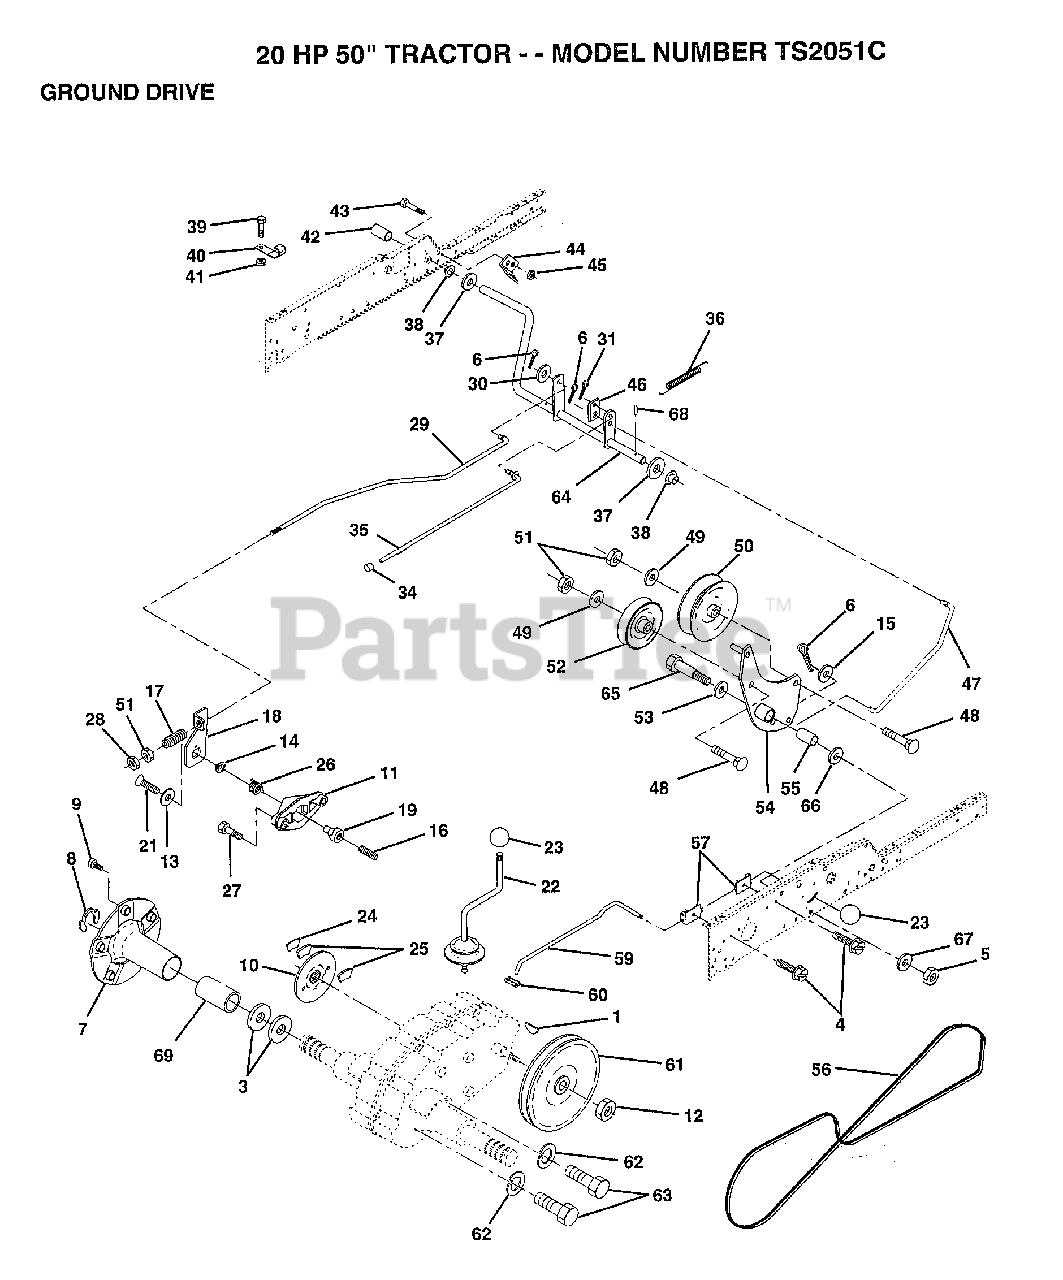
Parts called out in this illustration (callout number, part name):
3	WASHER T
6	COTTER PIN
8	KLIP RING
9	BOLT.HUB.WHL.REAR
11	YOKE BRAKE DISC
12	NUT STD
13	WASHER SPECIAL
14	BUSHING LEVER BKT
15	WASHER
16	SCREW SET 1/4-20
17	"SPRING,ROD BRAKE"
18	LEVER BRAKE GT
19	CAM BRAKE DISC GT
20	BOLT
21	SCREW FLT 1/4X28
22	GEAR SHFT LVR T
23	KNOB
24	SUPPORT PUCK BRKE
25	PUCK BRAKE TOP
26	SPRING RET BRAKE
27	SCREW HX WASH
28	NUT
29	ROD BRAKE ZINC GT
30	WASHER
34	PLUNGER CAP T
35	ROD BRAKE PART GT
37	WASHER
38	NYLINER T
39	SCREW
40	ACT-SWITCH T
42	PEDAL COVER T
43	BOLT LT
44	BRKT SWITCH GT
45	NUT
46	RETAINER SPRING
47	ROD.CLUTCH
48	BOLT
49	WASHER
50	FLAT IDLER PULLEY
51	NUT
52	PULLEY.IDLER.V.GR
53	WASHER T
54	ARM.ASM.IDLER.CLU
55	"LY, BEARING"
56	BELTV.GR.DR.83.
57	ROD BRACKET GT
58	NUT
59	ROD SHIFT HI LO
60	CONNECTING LINK
62	LOCKWASHER
63	BOLT
65	AXLE BOLT
66	WASHER.HARD.BLADE
67	WASHER
68	ROLL PIN STD
69	"COVER, HUB"
